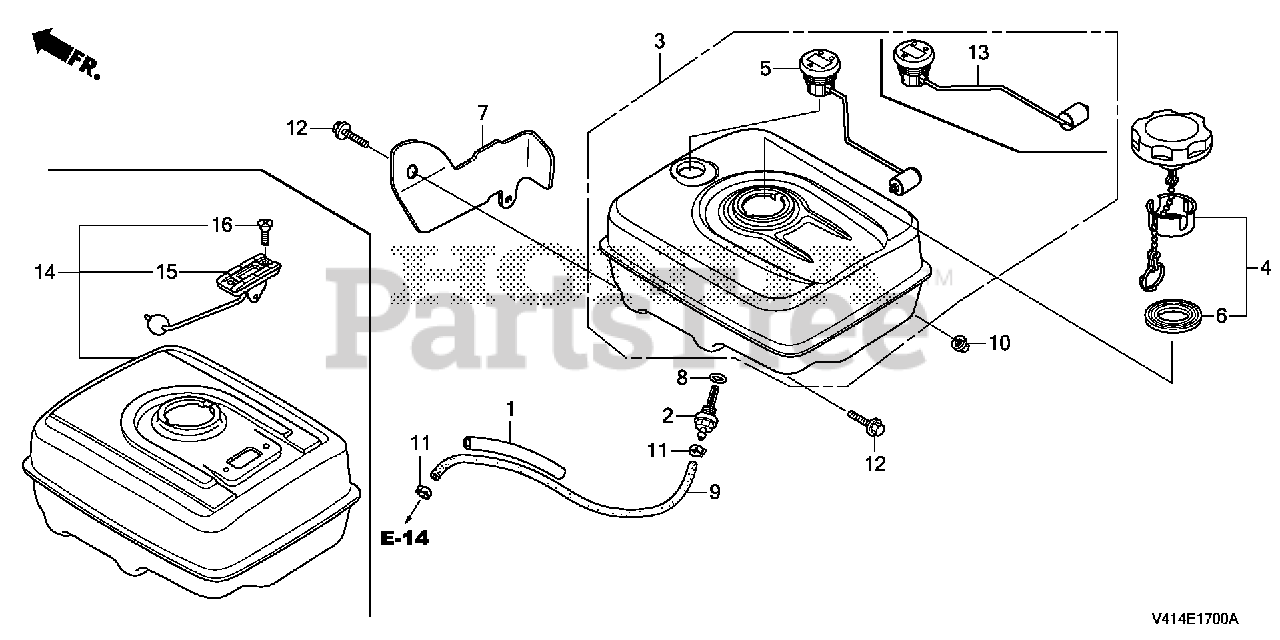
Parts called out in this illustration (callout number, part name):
1	RUBBER, SUPPORTER (107MM)
2	JOINT, FUEL TANK
3	TANK ASSY., FUEL *R280* (POWER RED)
4	CAP, FUEL FILLER
6	GASKET, FUEL FILLER CAP
6	GASKET, FUEL FILLER CAP (39X62X3) (TOUYOUSYA)
7	COVER, SNOW PLATE
8	O-RING (14MM) (ARAI) Use up to Engine SN 2949254.
8	O-RING (14MM) (NOK)
9	TUBE, FUEL (4.5X210) (FKM)
10	NUT, FLANGE (8MM)
11	CLIP, TUBE (D8)
12	BOLT, FLANGE (8X25)
13	GAUGE ASSY., FUEL
14	TANK ASSY., FUEL *NH31* (GAUGE) (MCKINLEY WHITE)
14	TANK ASSY., FUEL *R280* (GAUGE) (POWER RED)
16	SCREW, FLAT (5X10)
